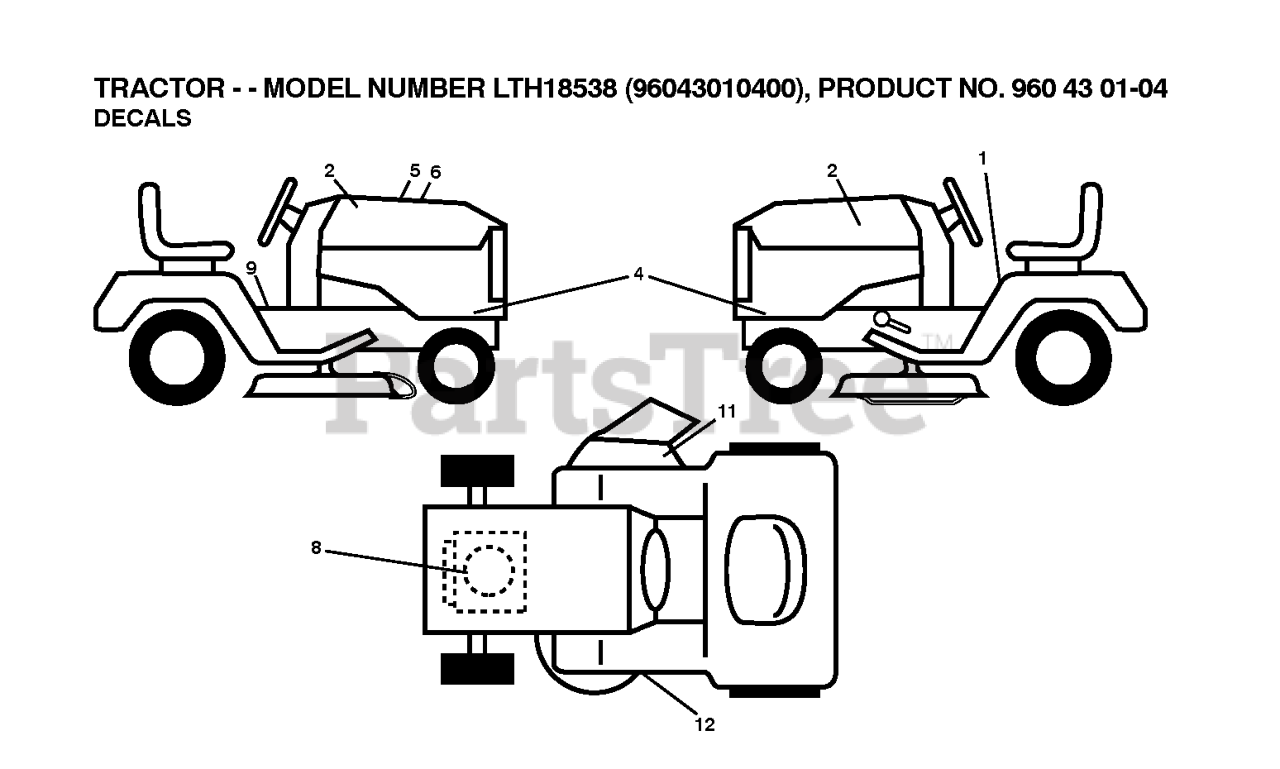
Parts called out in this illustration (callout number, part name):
1	DECAL.FENDER.WARNING.ENG
2	RP.DECAL.BADGE.170MM.TEXTLOGO
4	DECAL.SDPNL.LTH18538.B&S.HUS
5	DECAL.WARNING.CUST.RESP.E85.
6	DECAL, REPLACEMENT
8	DECAL, ENGINE HP
9	DECAL BTRY SYMBOLS
11	DECAL.WARN.KEEP.HAND.AWAY
12	DECAL.V-BELT.SCHEMATIC.36/38/9
